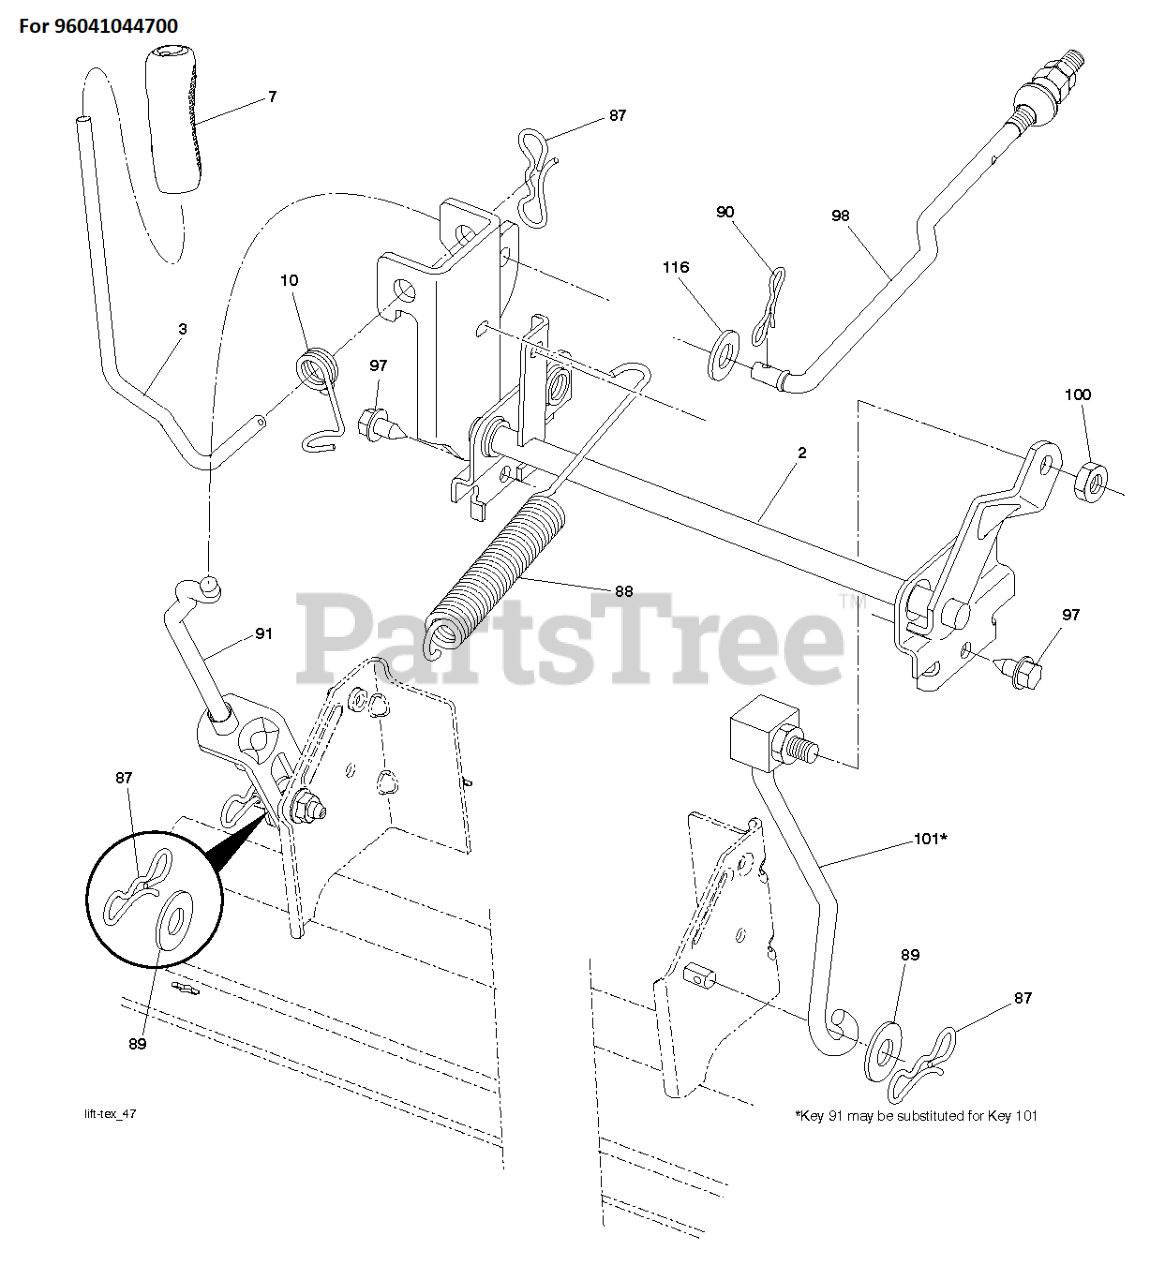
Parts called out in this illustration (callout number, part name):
2	SHAFT.ASM.CROSS.LIFT
7	GRIP.HANDLE.LIFT.PVC.BLACK
10	SPRING.TORSION.LIFT.HANDLE
87	PIN.COTTER.7/16.BOW TI.
88	SPRING.LIFT.ASSIST
89	WASHER.CLEAR.ZINC
90	PIN.COTTER.5/16.BOW TI
91	LINK ASSY LIFT.REAR 10.278
97	SCREW, 3/8-16X3/4
101	LINK.ASM.LIFT.FIXE.38/42/46"
